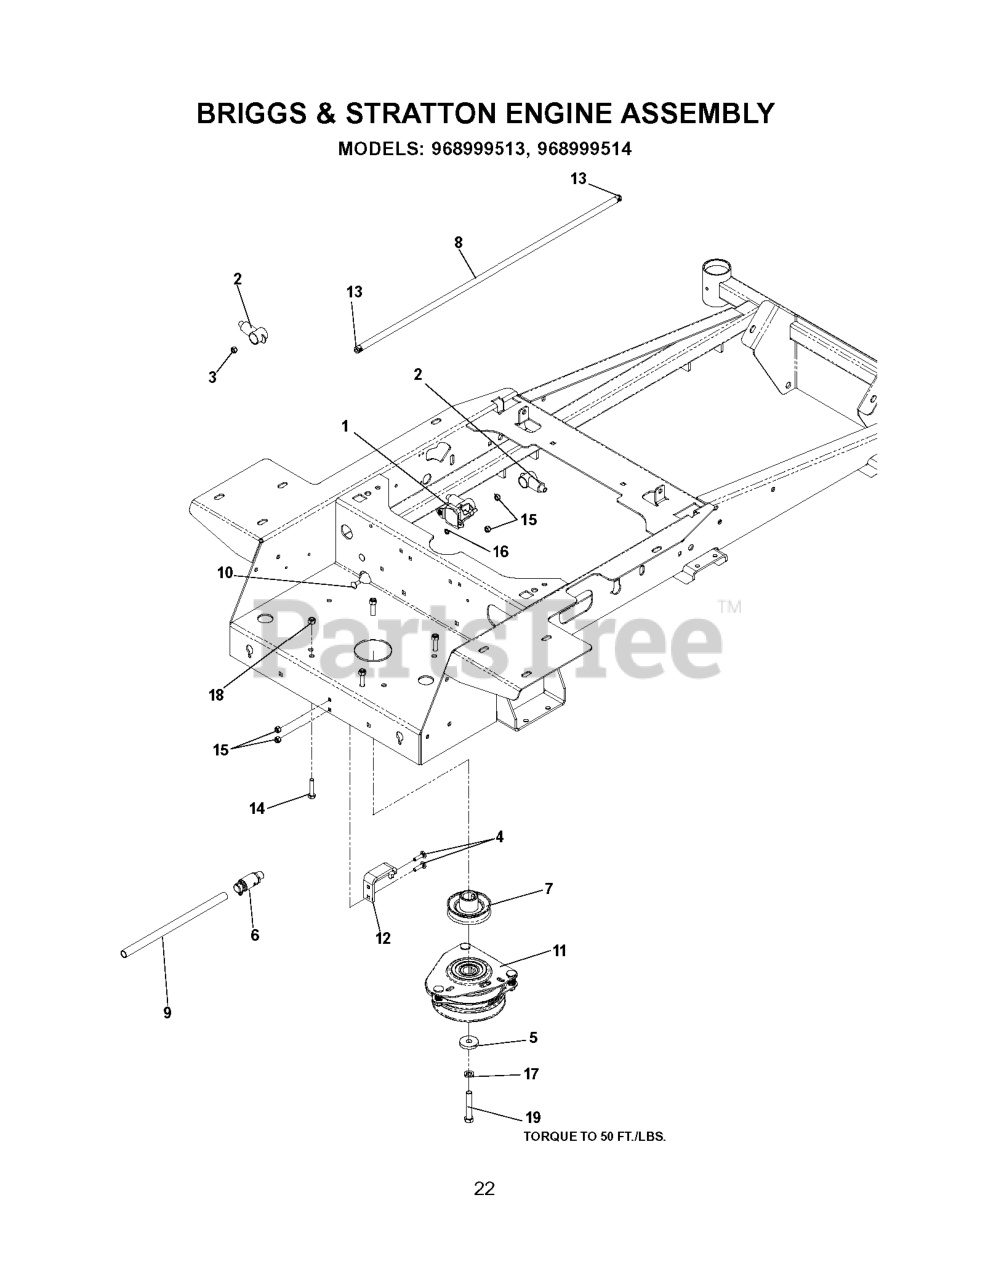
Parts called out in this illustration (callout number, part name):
3	JAM NUT 1/4C (2 2 PW01)
4	RHSNB, 1/4-20 X 1, GR5
5	CLUTCH, WASHER
6	OIL DRAIN FITTING
8	FUEL LINE 24"
9	FUEL LINE 5"
10	RHSSNB, 1/4-20X5/8
12	CLUTCH TIE DOWN
13	HOSE CLAMP
14	CAPSCREW 5/16 X 1/1/2 HEX HEAD
15	NUT.1/4-20.HEX.NYLOC.ZD
16	WASHER 1/4 INT TOOTH
17	WASHER 7/16 LOCK
18	NUT 5/16 NYLOC
19	BOLT 7/16F X 2 1/2
